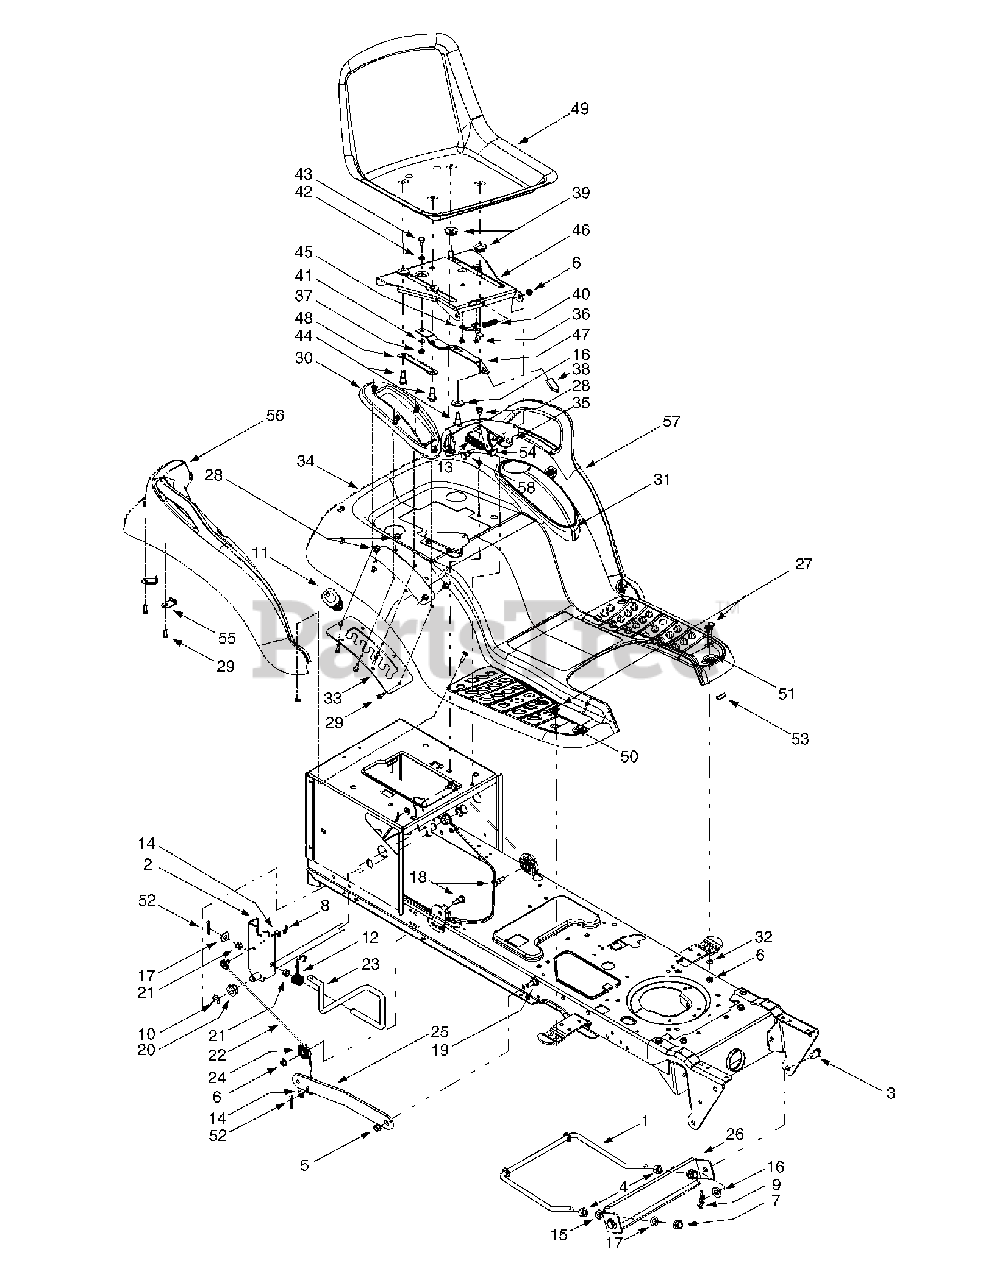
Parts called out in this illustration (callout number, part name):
1	Deck Stabilizer Rod (Model W814H)
2	Lift Shaft Assembly (Model W814H))
3	Clevis Pin, .5 x .78
4	Hex Nut, 1/2-13
5	Flange Lock Nut, 3/8-16
6	Flange Lock Nut, 5/16-18
7	Hex Nut, 1/2-13
8	Internal Cotter Pin
9	Internal Cotter Pin
10	E-ring
11	Handle Grip
12	Torsion Spring
13	Extension Spring, .84 x 4.6
14	Flat Washer, 5/16
15	Lock Washer, 1/2
16	Flat Washer, .31 x 1.062 x .134
17	Flat Washer, .51 x 1.12 x .06
18	Hex Cap Screw, 5/16-18 x .62
19	Shoulder Screw, 3/8-16
20	Hex Flange Bearing
21	Snap Flange Bearing
22	Lift Cable, 16.16
23	Lift Handle
24	Roller Pulley
27	Carriage Bolt, 5/16 x .62
28	Self-tapping Screw, 5/16-18 x .625
29	Self-tapping Screw, 1/4-15 x .75
30	Lift Lever Cover
31	Cover w/ Cup Holder
32	Flat Washer, .349 x 1.0 x .063
36	Screw, #10-16 x .375
37	Hex Flange Lock Nut, 1/4-20
38	Seat Adjuster Grip
39	Spacer
40	Compression Spring, .41 x 1.5
41	Spring Washer, .265 x .562 x .025
42	Flat Washer, .344 x .62 x .03
43	Shoulder Screw, .340 x .285,1/4-20
44	Shoulder Screw, .50 x .50, 3/8-16
45	Seat Stop
48	Seat Adjustment Selector
49	Seat, Yellow
50	RH Foot Pad
51	LH Foot Pad
52	Cotter Pin
53	Trim Strip
54	LH Seat Lift Bracket
55	Fender Clips
56	RH Fender Flare
57	LH Fender Flare
58	Shoulder Screw, .437 x .286
